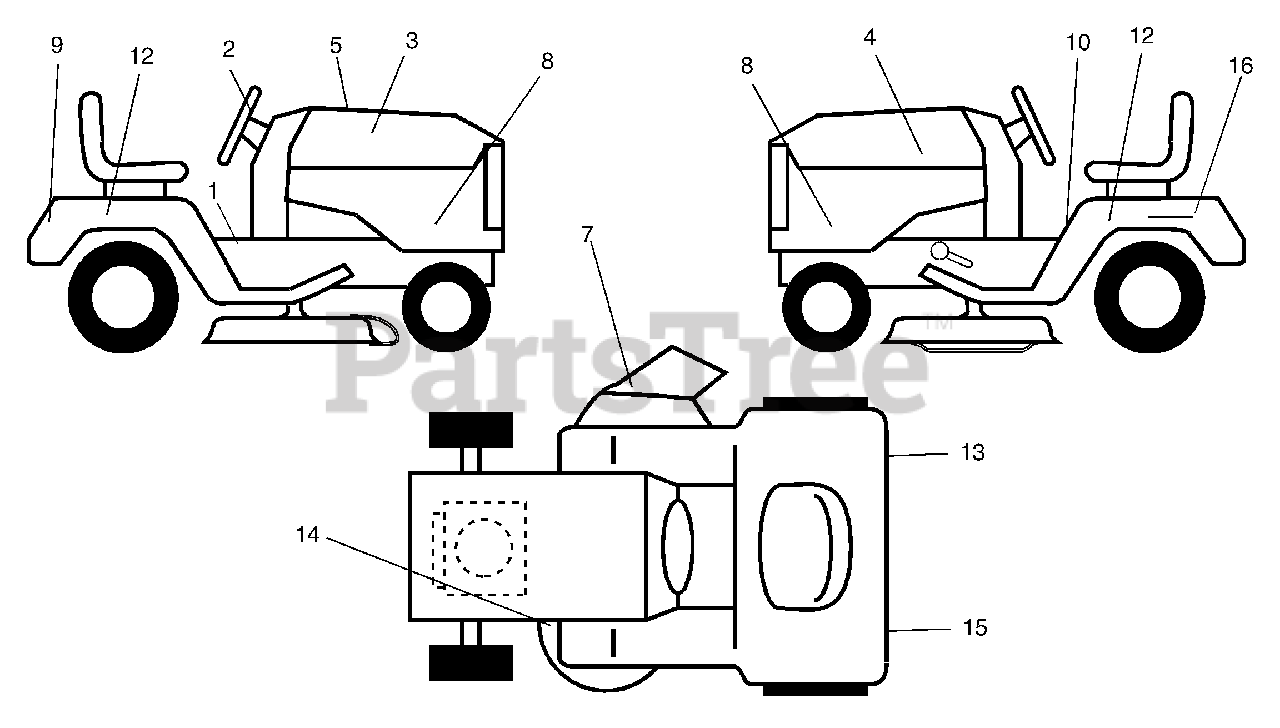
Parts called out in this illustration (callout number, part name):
1	Decal Instruction Operat English/French
2	Decal Ins Strg Wh
3	Decal Hood Rh
4	Decal Hood Lh
5	Decal Replacement
7	Decal Deck "B" 42"
8	Decal Hood Side Panel
9	Decal Fender Logo
10	Decal Danger English
12	Decal Fender
13	Decal Reflector LH
14	Decal V-belt Schematic 42"
15	Decal Reflector RH
16	Decal Battery Danger/Poison
20	Decal HP Engine
